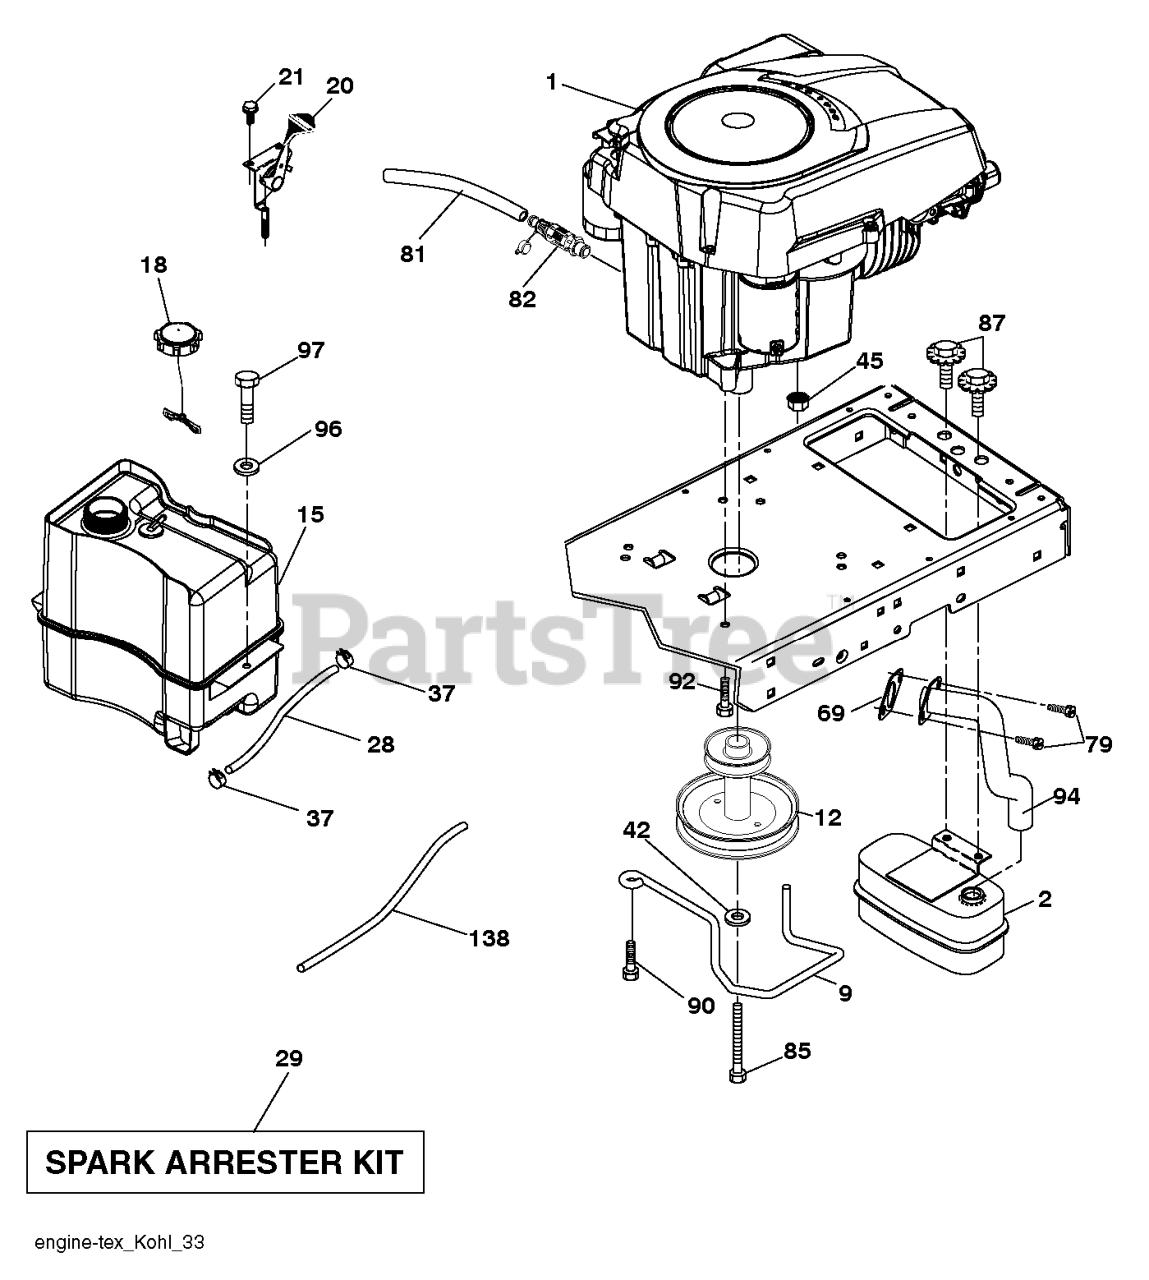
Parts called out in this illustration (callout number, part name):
2	MUFFLER.SINGLE.CYL.KOHL/B&S
9	KEEPER.BELT.ENGINE.4.2
12	RP_PULLEY ENGINE
15	TANK.ASM.FRT.2.5 GAL.W/CAP.EPA
18	CAP.2.25'.VENTED.TETHER .EPA
20	CONTROL.TH/CK.COBRA.KO
21	SCREW.#10 X 0.750.BOS
28	LINE.FUEL.20"FRONT.EMI
29	KIT.SPARK ARRESTOR 794945 B&S
37	HOSE CLAMP
42	LOCKWASHER
45	NUT
69	GASKET.EXHAUST.KOHLER
79	SCREW.SOCKET HD.5/16-1
81	TUBE, DRAIN OIL ASM.
82	VALUE.OIL.DRAIN
85	BOLT HEX 7/16-20X4-1/4"
87	BOLT 5/1618UNC X 3/4 W/ SEMS
90	SCREW 3/8-16X1
92	SCREW 3/8-16X1
94	RP.TUBE.EXHAUST.KOHL.COURAGE
97	SCREW HEXWSHR 1/4-20X3/4
138	RP PURGE LINE
